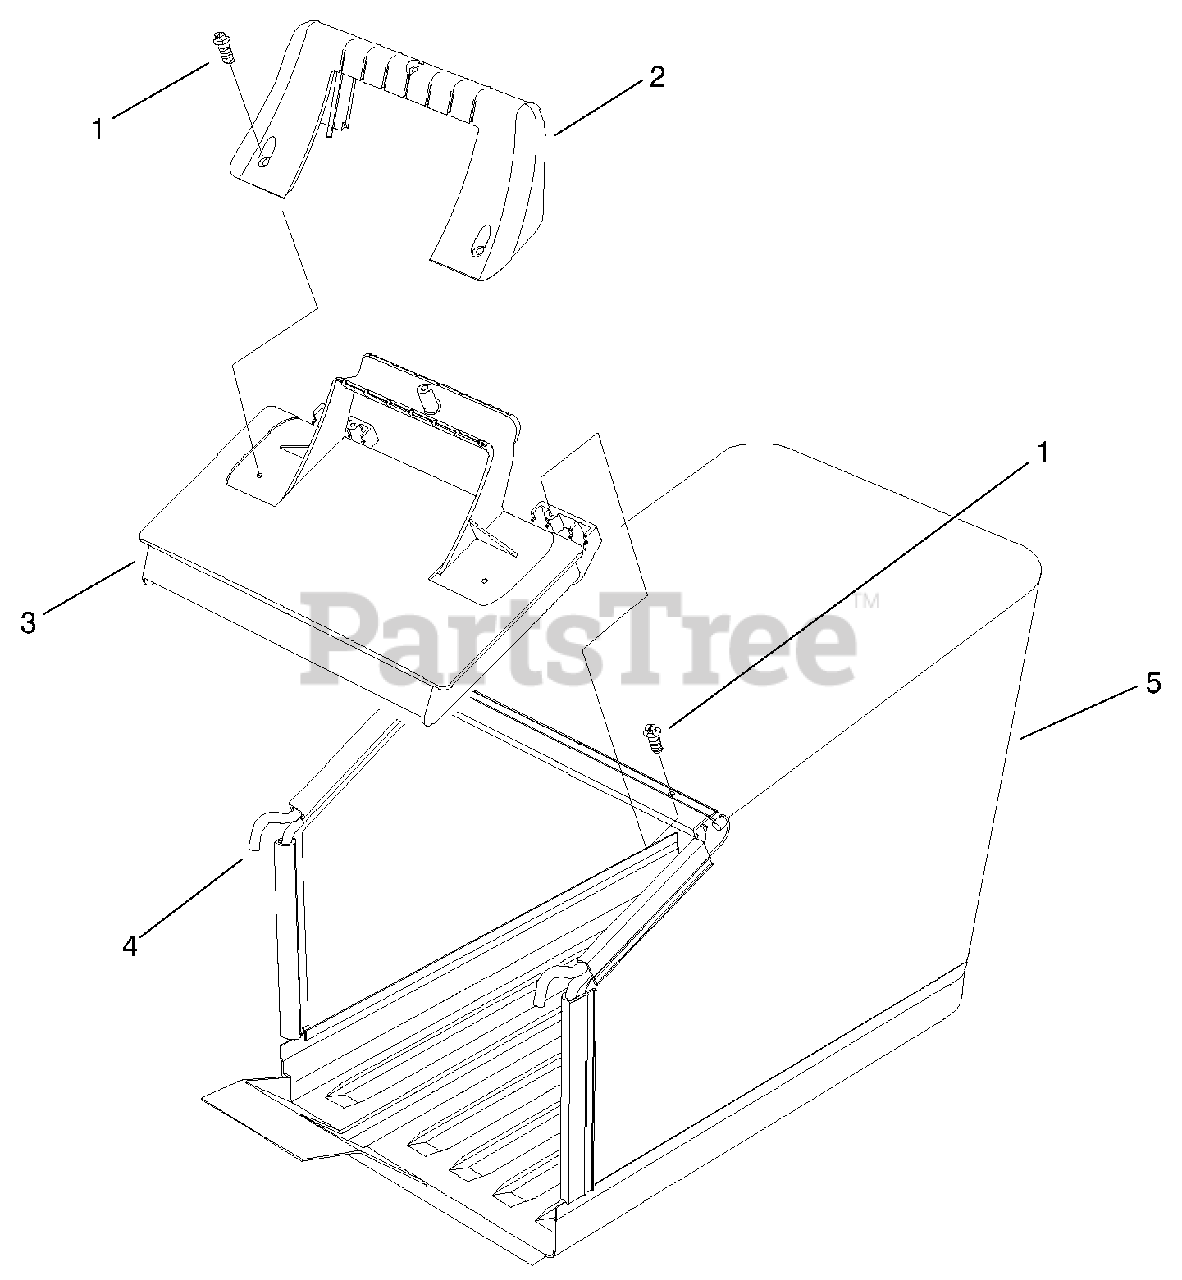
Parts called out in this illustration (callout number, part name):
1	Screw-PPH
2	Handle-Door
3	Bag Door
5	Bag-Grass
